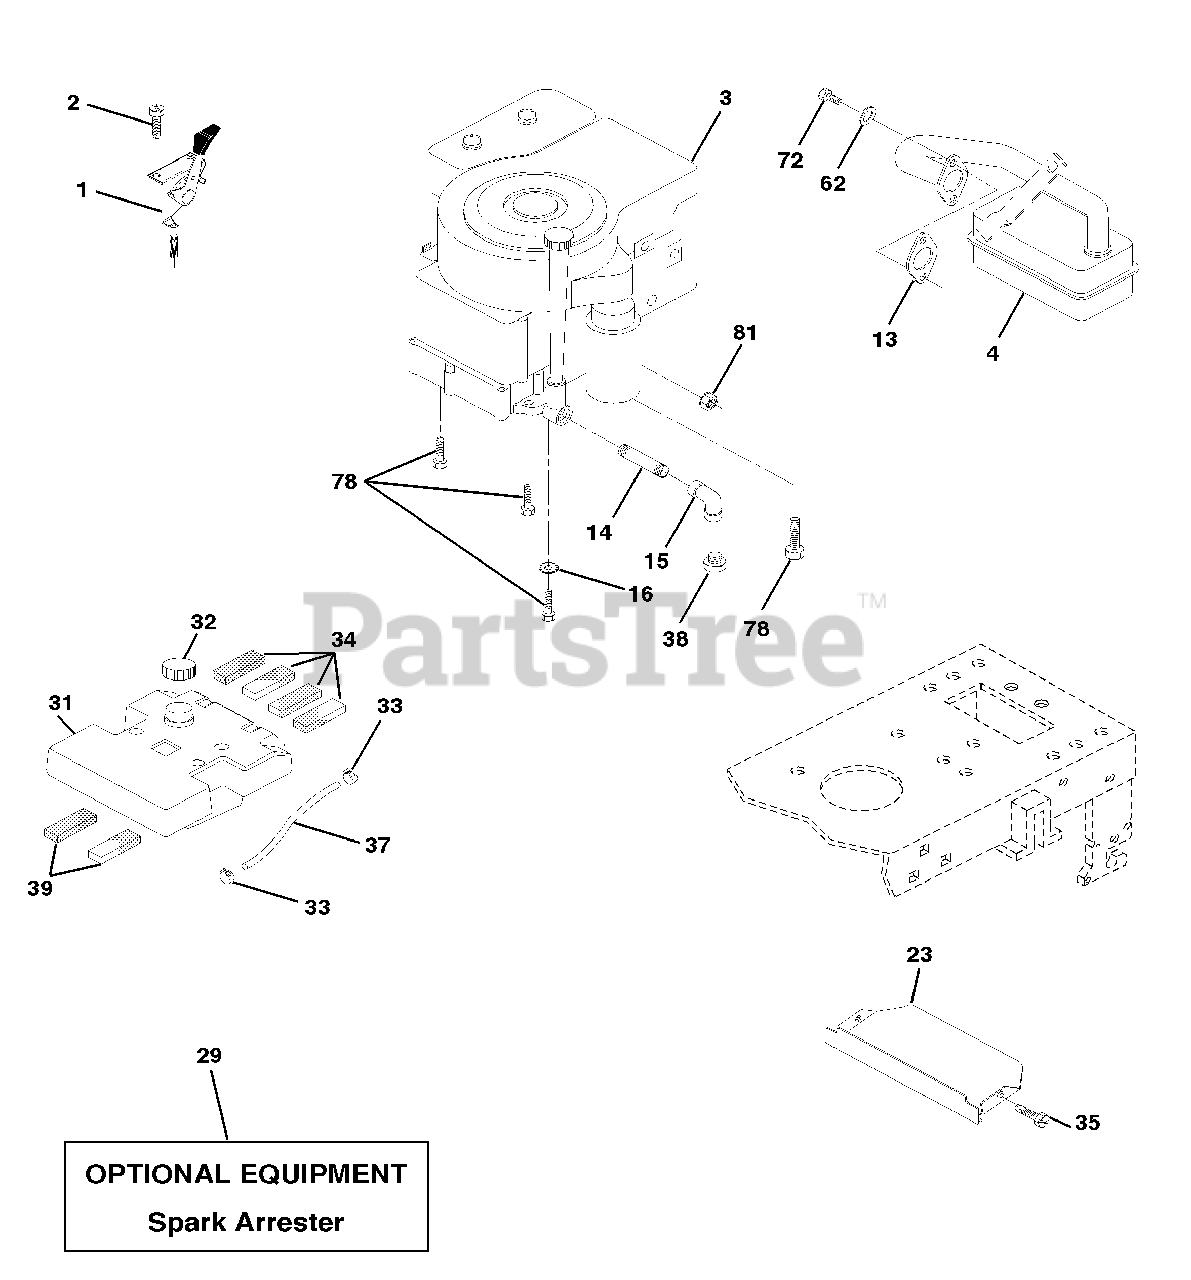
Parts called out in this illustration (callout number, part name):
1	Control Th/ch 23.5 LH. Flag
2	Screw Hex Thd Cut 1/4-20x5/8 T
4	Muffler Exh Lt B&S 14 HP IC OHV
13	Gasket B&S Tin Plated
14	Nipple Pipe 3/8 Npt X 3
15	Elbow Std 90 Degree 3/8-18 Npt
16	Washer Lock Ext Tooth 3/8
23	Shield BRN/DBR Guard
29	Kit Spark Arrestor (Flat Scrn)
31	Tank Fuel 3.5 STLT W/O Sensor
32	Cap Asm Fuel W/sym Vented
33	Clamp Hose Black
34	Pad Spacer
35	Screw
37	Line Fuel 7.5"
38	Plug Oil Drain
39	Pad Idler 1.75 x .75 x .06
62	Washer Lock Hvy Hlcl Spr 5/16
72	Screw Hex Hd Cap 5/16-18 x 3/4
78	Screw Thdrol 3/8-16 x 1-1/4
81	Nut Flange 1/4-20 Starter Nut
